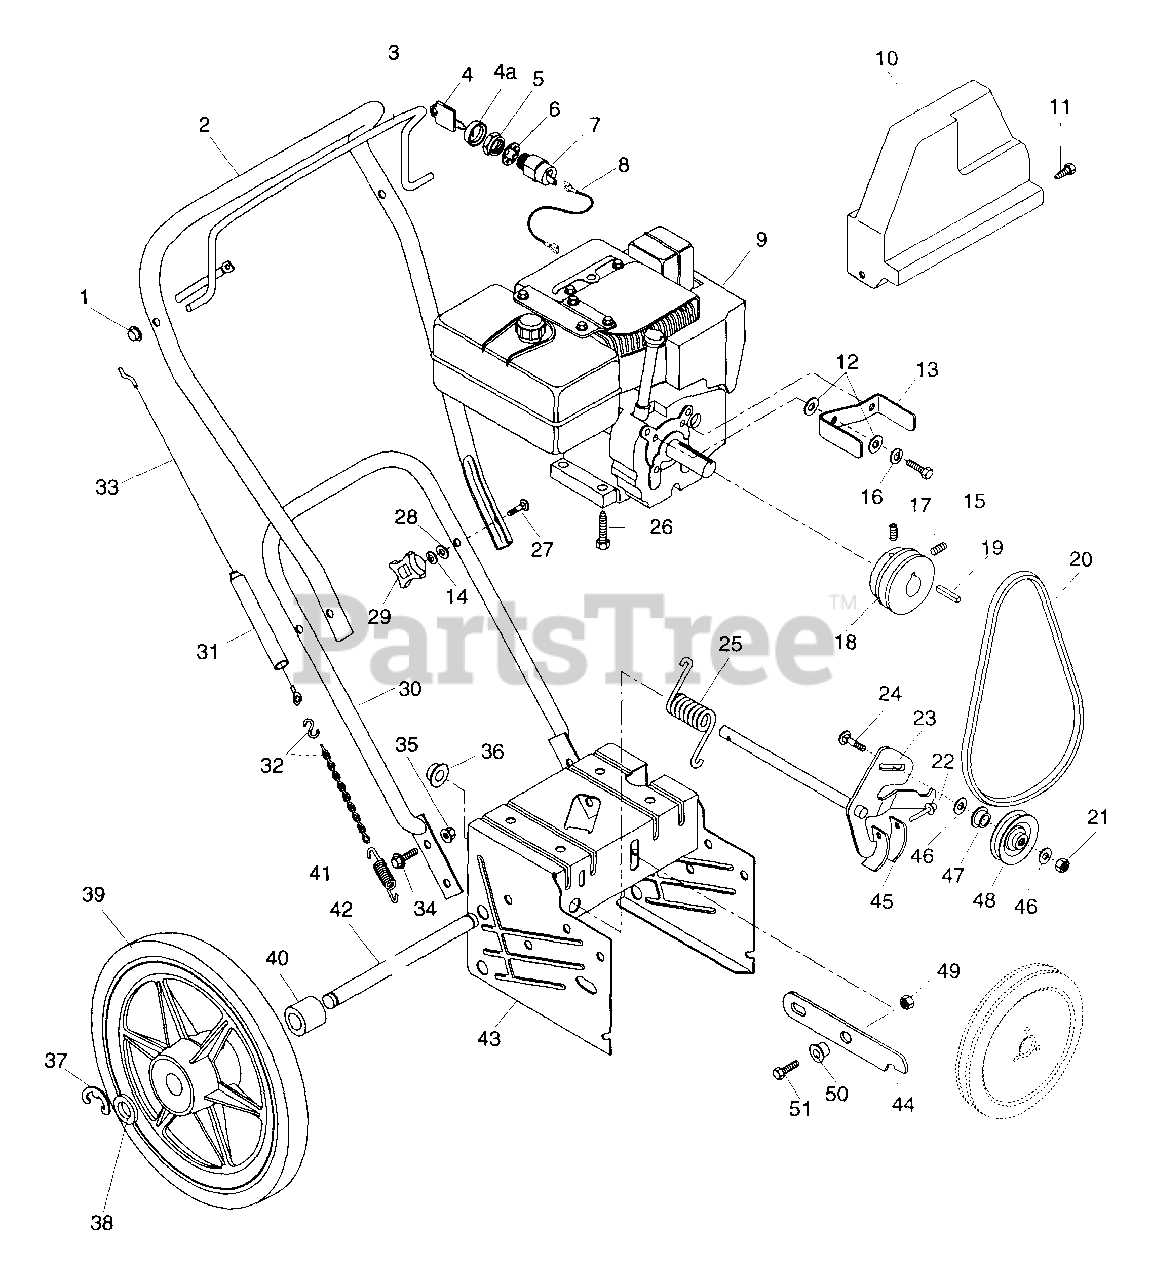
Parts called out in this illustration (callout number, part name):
1	NUT-PUSH .312 DIA. PAL
2	UPPER HANDLEBAR
3	BAIL
4	KEY -W/CAP
4A	CAP - IGNITION SWITCH
5	NUT .625-32 ALUM
6	WSHR-LK-INT .625X.045 PL
7	SWITCH
8	WIRE
9	ENGINE-HSSK 50 TEC NO PTO
10	BELT COVER
11	SCR-TAP .250-20X.37 HWH PL TR
12	WSHR-FL-STL .380X.875X.179 PL
13	BELT FINGER
14	WSHR-LK .312X.097 PL HVY
15	BLT-HEX .31-24X.75 PL GR5
16	WSHR-LK .313X.093 MED HICLR
17	SCR-SET .31-18X.38 SKHCUPDL
18	ENGINE SHEAVE
19	KEY-SQ .188X1.0X.188 SAE 8630
20	V-BELT, 4L-COGGED
21	NUT-LK .312-18 GR A PL
22	RVT-TBLR .187X.437 RH ST PL
23	BRAKE CLUTCH ARM W/LINING
24	BLT-RDHDSQNK .31-18X1.38SHT PL
25	SG-TORS .148X1.0X1.53
26	SCR-TAP .375-16X1.0 HWH PL TR
27	BLT-CRVD-HD .31-18X3.0 PL
28	WSHR-FL-STL .323X.625X.062 PL
29	KNOB 5/16-18 UNC
30	LOWER HANDLEBAR
32	CHAIN & CONNECTOR
34	BLT-SERHFWH .31-18X.62 PL
35	NUT-FLG. .312-18 PL
36	CAP, .50 ROD YWZC
37	RG-RTNG-EXT .500X.042 (E)
38	WSHR-FL-STL .505X.880X.072 PL
39	WHEEL - 16 X 1.75 X .562
40	AXLE SPACER
41	SG-TENS .091X.56X4.25 WLD 40
44	ARM
45	BRAKE LINING
46	WSHR-FL-STL .38X.875X.083 PL
47	SPCR, BRG .315X.50X.688X.281
48	IDLER
49	NUT-LK-CTR .250-20 PL
50	BSHG-FLG .265X.437X.250X.750
51	BLT-HEX .25-20X.63 PL GR2
